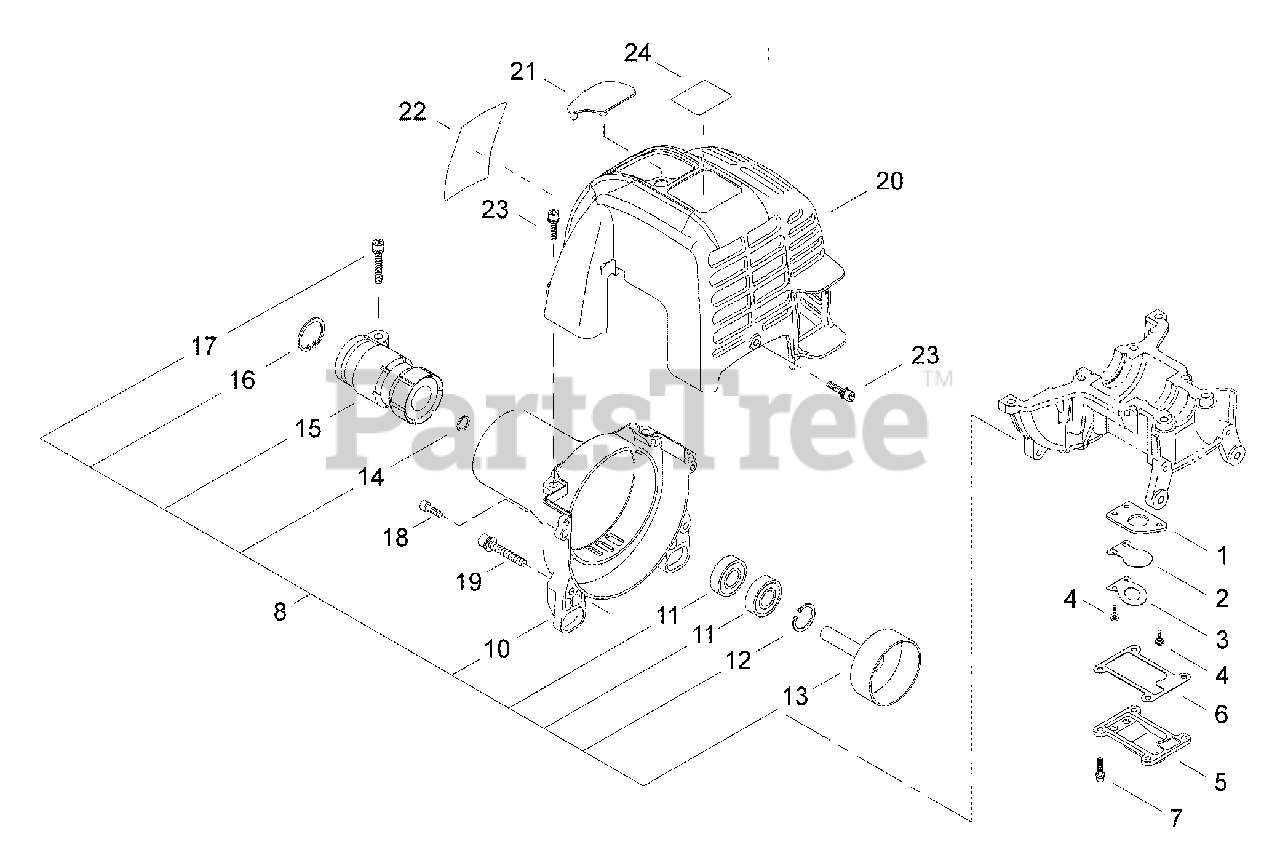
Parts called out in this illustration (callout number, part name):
1	PLATE, REED BACKING
2	VALVE, REED
3	STOP, REED VALVE
4	SCREW M3×10
5	COVER, REED VALVE
6	GASKET, REED VALVE
7	BOLT M4×14
8	COVER ASSY, FAN
10	COVER, FAN
11	BEARING, BALL 6001 DDU C3
12	RING, SNAP Ø28
13	DRUM, CLUTCH
14	RING, SNAP Ø12
15	CUSHION, AV
16	RING, SNAP Ø42
17	BOLT M5×22
18	BOLT 5×16
19	BOLT M5×40
20	COVER, ENGINE
21	COVER, SPARK PLUG
22	LABEL, C4 SHINDAIWA
23	BOLT M4×14
24	LABEL, C3410
